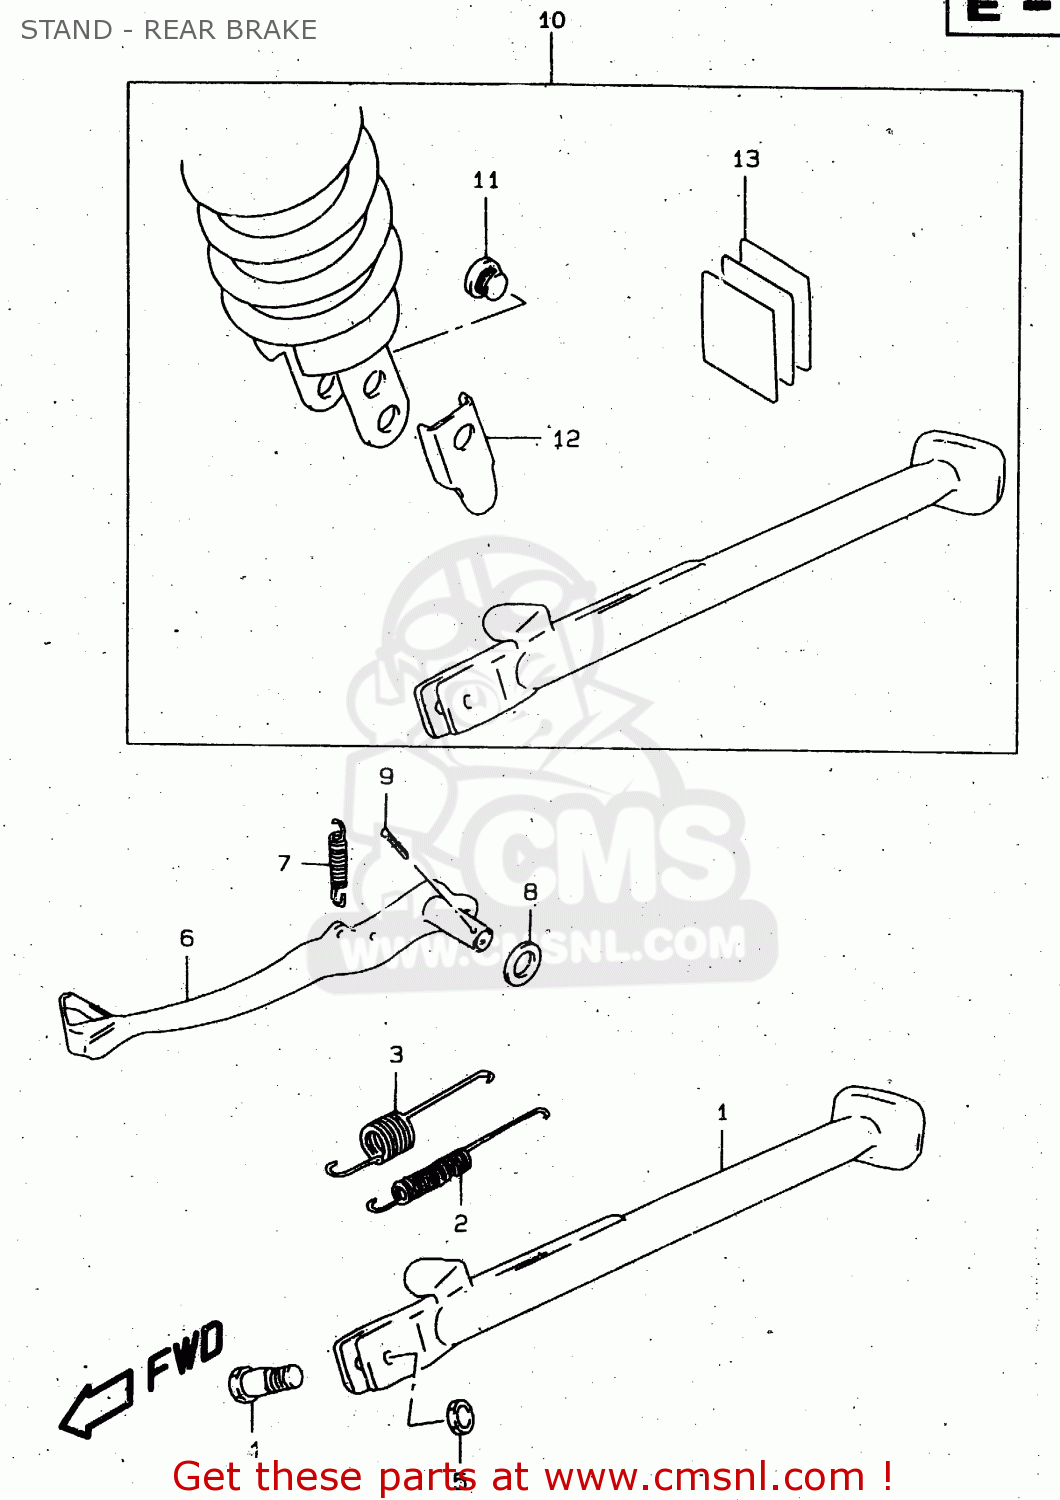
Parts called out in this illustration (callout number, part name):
1	STAND,PROP
2	SPRING
3	SPRING
4	BOLT(10X30)
5	NUT
6	PEDAL,BRAKE
7	SPRING
8	WASHER(15.5X26X2.3)
9	COTTER PIN
10	Low Side Stand
11	PLUG
12	PLATE,RR SHOCK ABSORBER LWR
13	LABEL SET,WARNING
